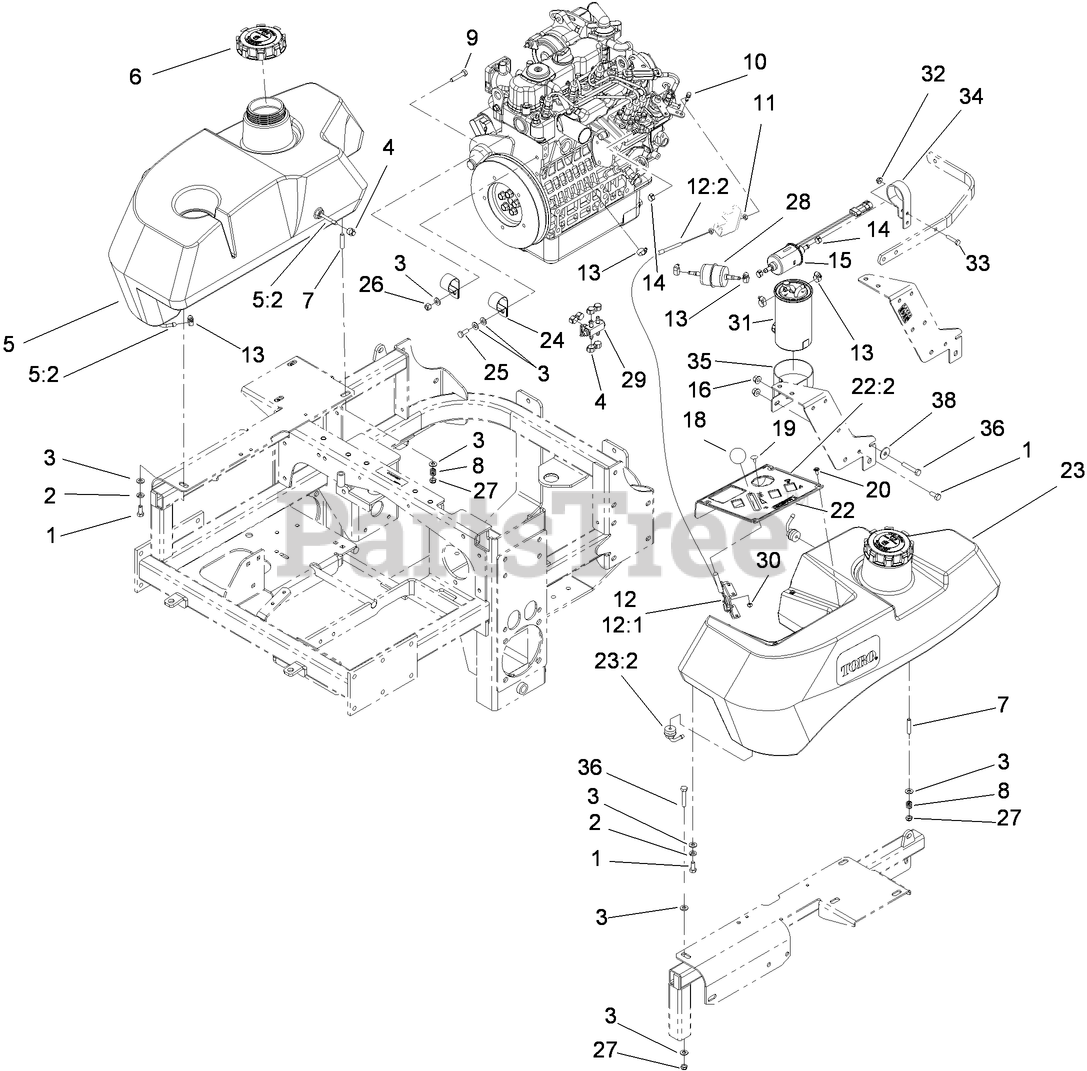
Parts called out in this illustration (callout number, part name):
1	SCREW-HH
2	WASHER-LOCK
3	WASHER-PLAIN
4	CLAMP-HOSE, FUEL
5	RH FUEL TANK ASM
5:2	Fitting-Fuel, Bulkhead
6	BIODIESEL CAP ASM
8	SPRING-TANK, FUEL
9	SCREW-HH
10	SWIVEL-STOP, CABLE
11	NUT-JAM
12	THROTTLE CONTROL ASM
12:1	LEVER-THROTTLE
12:2	CABLE-THROTTLE
13	CLAMP-WORM
14	CLAMP-HOSE, FUEL
15	PUMP-FUEL
16	NUT-LOCK, NI
18	KNOB-BALL
19	BOLT-CARR
20	SCREW-PPH
22	CONTROL PANEL ASM
22:2	DECAL-PANEL, CONTROL
23	LH FUEL TANK ASM
23:2	Fitting-Fuel, Bulkhead
24	CLIP-LOOM
25	SCREW-HH
26	NUT-LOCK, NI
27	NUT-LOCK, NI
28	FILTER-INLINE
29	VALVE-FUEL, DUAL FLOW
30	NUT-LOCK, NI
31	ELEMENT-FILTER, FUEL/WATER
32	NUT-HF
33	SCREW-HH
34	BRACKET-PUMP, FUEL
35	BRACKET-FILTER, FUEL
36	SCREW-HH
38	WASHER-FLAT
